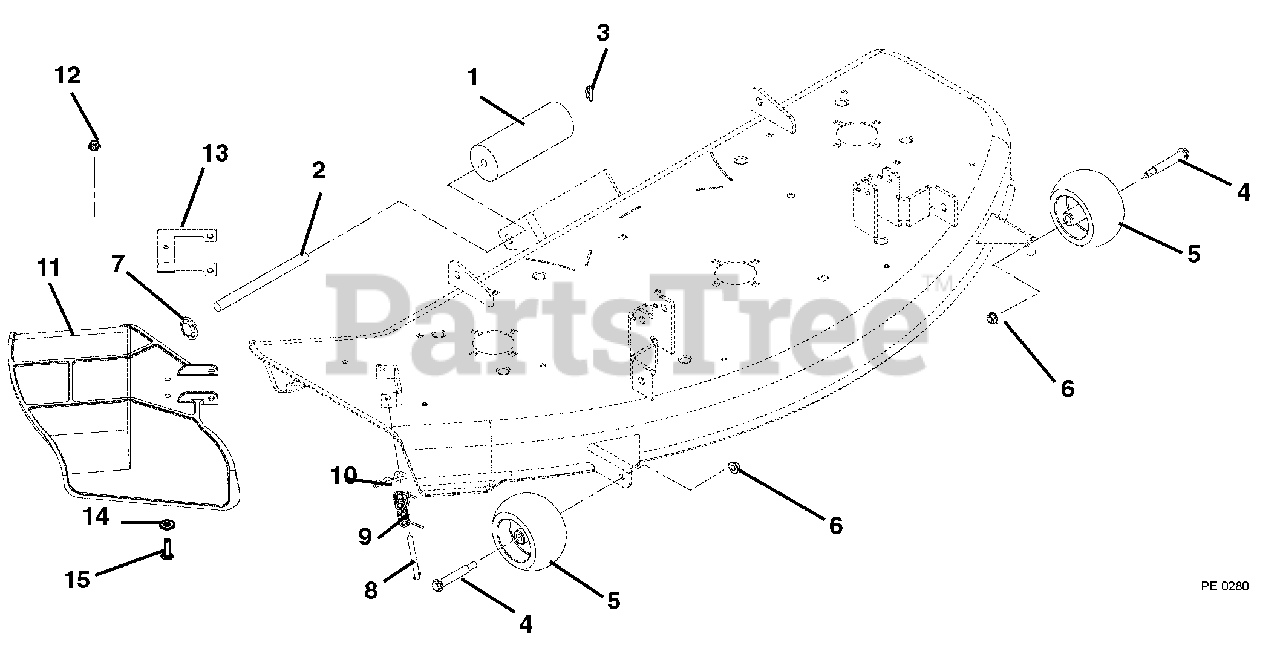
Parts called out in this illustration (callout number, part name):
1	ROLLER
2	PIN, ROLLER
3	PIN, SPRING CLIP
4	BLT-SHLDR .38-16X2.50 HWH G5
5	WHEEL 5 X 3
6	@NUT-LK-TOP-FLG .38-16 YWZC
7	PUSH NUT, .625 SHAFT
8	PIN, 5/16 X 3.88"
9	SPRING, TORSION
10	PIN-HAIR INT .08X.18X1.18 YWZC
11	MOLDED CHUTE, ZOOM
12	@NUT-LK-TOP-FLG .31-18 YWZC
13	CHUTE REINFORCEMENT
14	@WSHR-FL-STL.38X.875X.083 YWZC
15	SCR-SKH .31-18X.75 BTNHD YWZC
